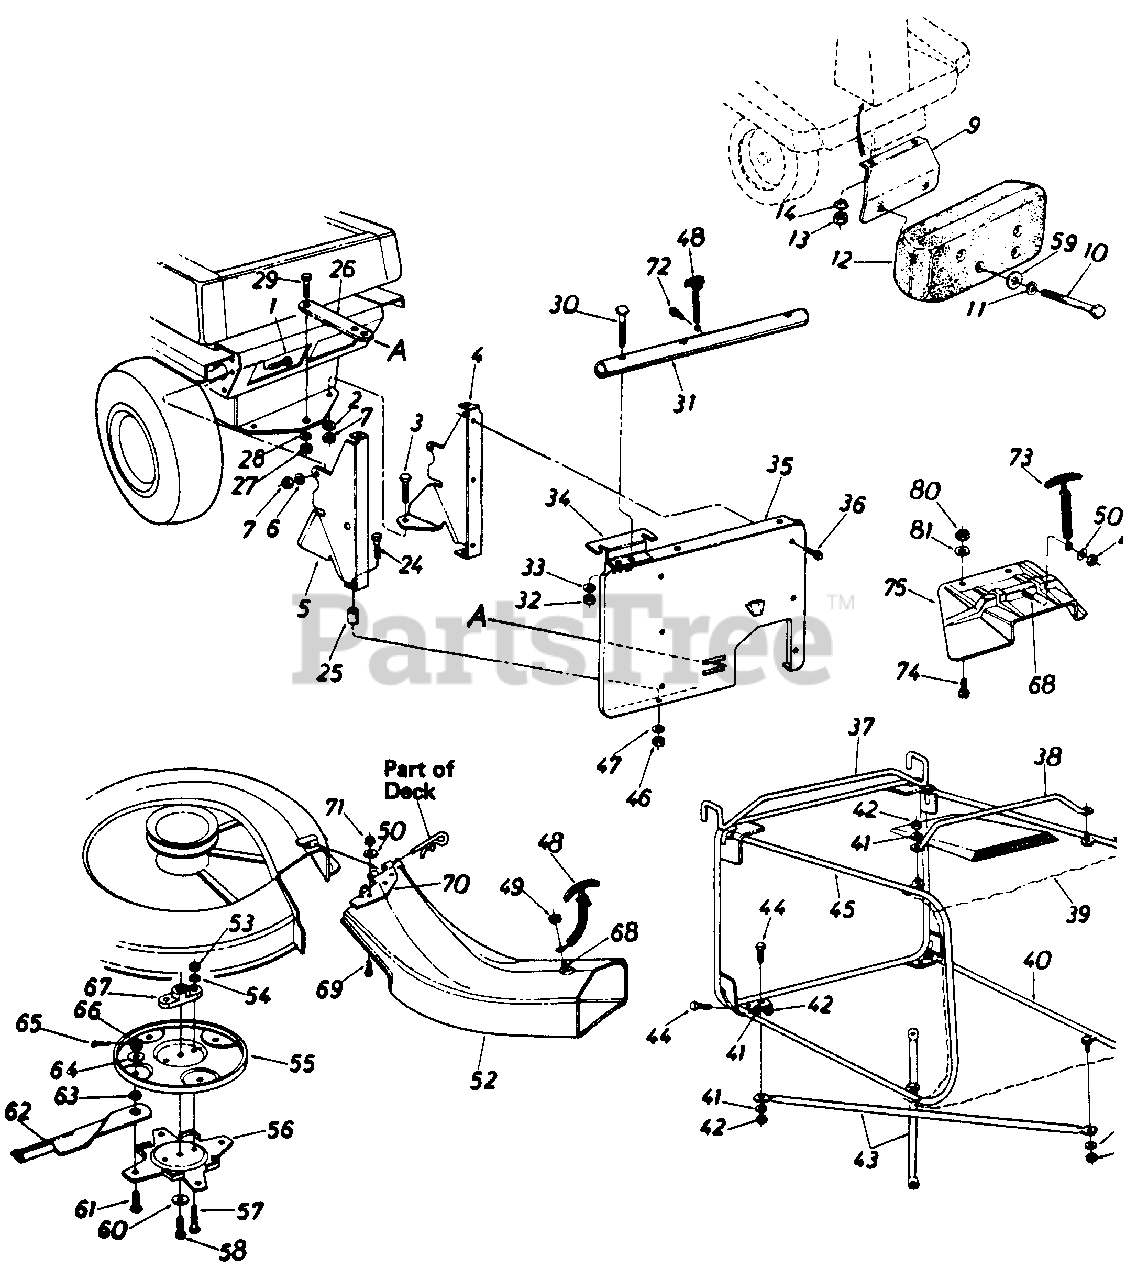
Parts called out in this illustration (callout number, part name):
1	Hex Bolt 5/16-18 x 1.0" Lg.
2	L.-Wash. 5/16" I.D.
3	Hex Bolt 5/16-18 x 1.0" Lg.
4	Catcher Support Brkt-R.H.
5	Catcher Support Brkt-L. H.
6	L.-Wash. 5/16" I.D.
7	Hex Nut 5/16 18 Thd.
9	Counterweight Support Brkt. Ass'y.
10	Hex Bolt 3/8-16x 4.5" Lg.
11	Bellevllle Wash. .40" I.D. 88" O.D.
12	Counterweight 38 Ibs.
13	Hex Nut 5/16-18 Thd.
14	L.-Wash. 5/16" I.D.
24	Hex Bolt 5/16-18 x 1.5O" Lg.
25	Spacer .380" I.D. x .47" O.D. x 1.0" Lg.
28	L.-Wash. 1/2" I.D.
29	Hex Bolt 1/2-20 x 1.0" Lg.
30	Curved Carriage Bolt 5/16-18 x 1.75" Lg.
33	L.-Wash. 5/16" I.D.
34	Grass Catcher Support Plu
35	Rear Discharge Panel
36	Hex Wash. Hd. Self-Tap. Scr. 1/4-20 x .5O" Lg.
37	Grass Catcher Frame Ass'y.
42	Hex L-Nut 1/2-20 Thd
43	Bottom Cross Brace
44	Hex Bolt 1/4-20 x .62" Lg.
47	L-W-sh. 5/16" I.D.
48	Hook Latch Ass'y.
49	Hex L.-Nut 1/4-20 Thd.
50	L-Wash. 1/4" I.D.*
52	R.D. Banana Chute Ass'y.
53	Hex Nut 5/l6-2a 'hd.
54	L.-Wash. 5/16" I.D.
55	Upper Blade Disc
58	H-x Bolt 3/8-24 x 1.0" Lg.
59	Fl.-Wash. .39" I.D. x 1.12" O.D.
60	Bell.-Wash. 39" I.D. x 1.38"
61	Shld. Bolt. .50" Dia. x .360 Spec.
62	30" Blade Tip
63	Spacer .505"1 .D. x .75" O.D. x 1.25" Lg.
64	Fl.-Wash. .50" I.D. x 1.25" O.D.
65	Cotter Pin 3/32" Dia. x 1.0" Lg.'
66	Hex Slotted Nut 1/2-20 Thd.
67	Blade Adapter
68	Hex Bolt 1/4-20 x .50" Lg.
69	Truss Mach. Scr. 1/4-20 x .50" Lg.
72	Hex AB Tap Scr. 1/4 x .62"
73	Hook Latch Ass'y. 7" Lg.
74	Truss Mch. Scr. 1/4-20 x 50" Lg.
75	R D Chute Extension
80	Hex L.-Nut 1/4-20 Thd.
81	Fl.-Wash. .281" I.D. x .50" O.D. .063
